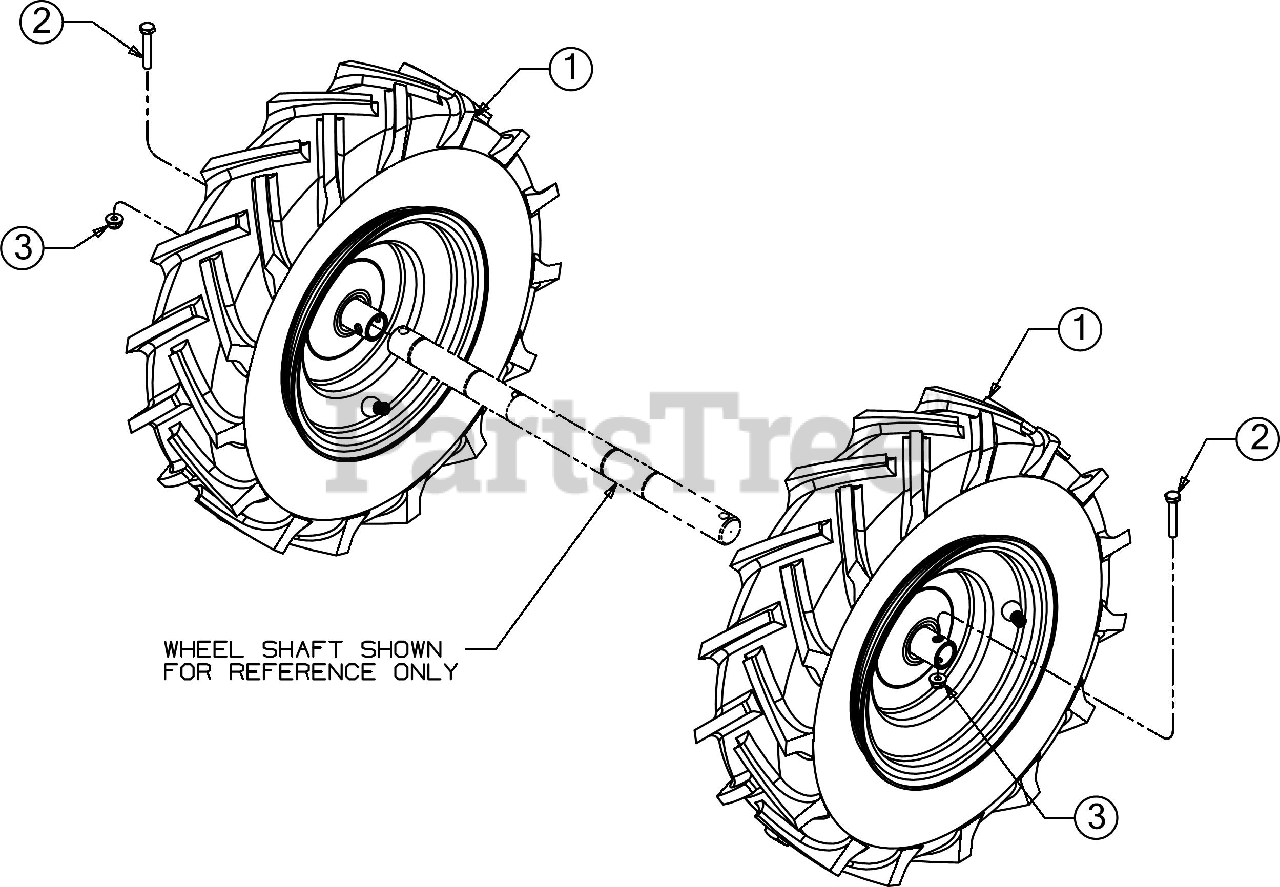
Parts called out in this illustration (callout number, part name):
1	WHEEL ASSEMBLY (16 X 4.6 X 8)
1	RIM ASSEMBLY (8.0 X 3.75 X .757)
1	TUBELESS VALVE
1	TIRE 16.25 X 4.5-8
2	SCREW 1/4-20 X 1.50 GR8
3	FLANGE LOCK NUT
